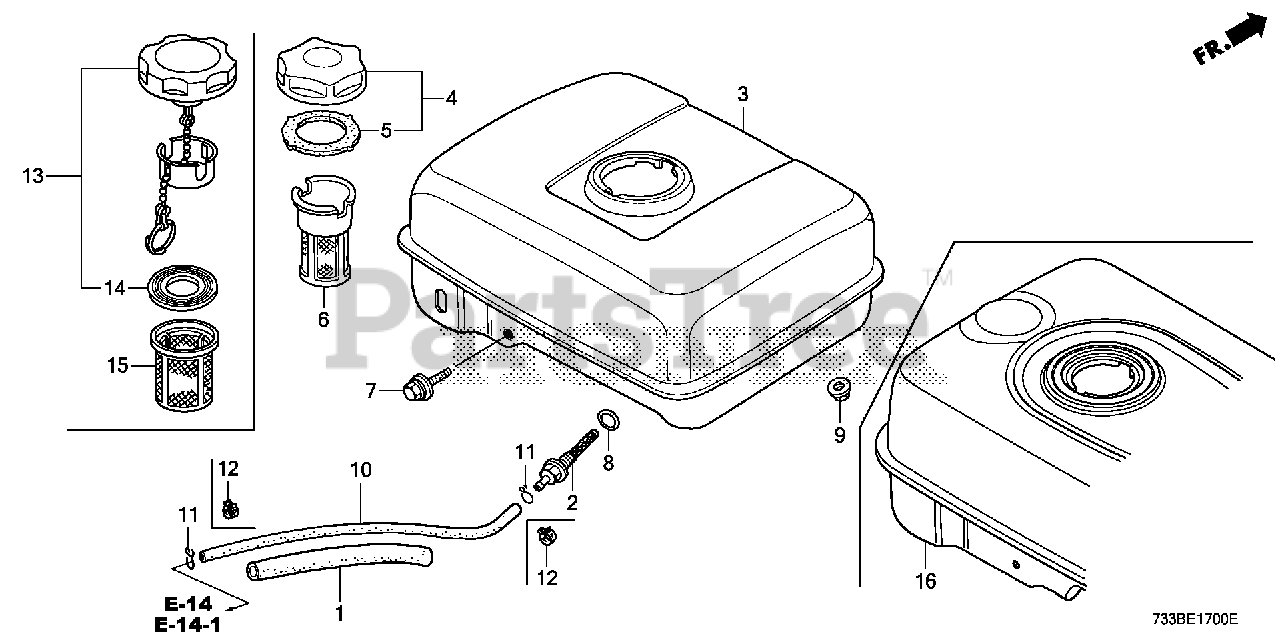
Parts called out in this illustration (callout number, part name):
1	BULK HOSE, VINYL (9X11X3000) (9X11X140)
2	JOINT, FUEL TANK
3	TANK, FUEL *R280* (POWER RED)
7	BOLT, FLANGE (6X29)
8	O-RING (13.5X1.5) (ARAI)
8	O-RING (14MM) (NOK)
9	NUT, FLANGE (6MM)
10	TUBE, FUEL (4.5X175) (FKM)
12	CLAMP, TUBE (D8)
13	CAP, FUEL FILLER
14	GASKET, FUEL FILLER CAP (39X62X3) (RADICON)
15	FILTER, FUEL
